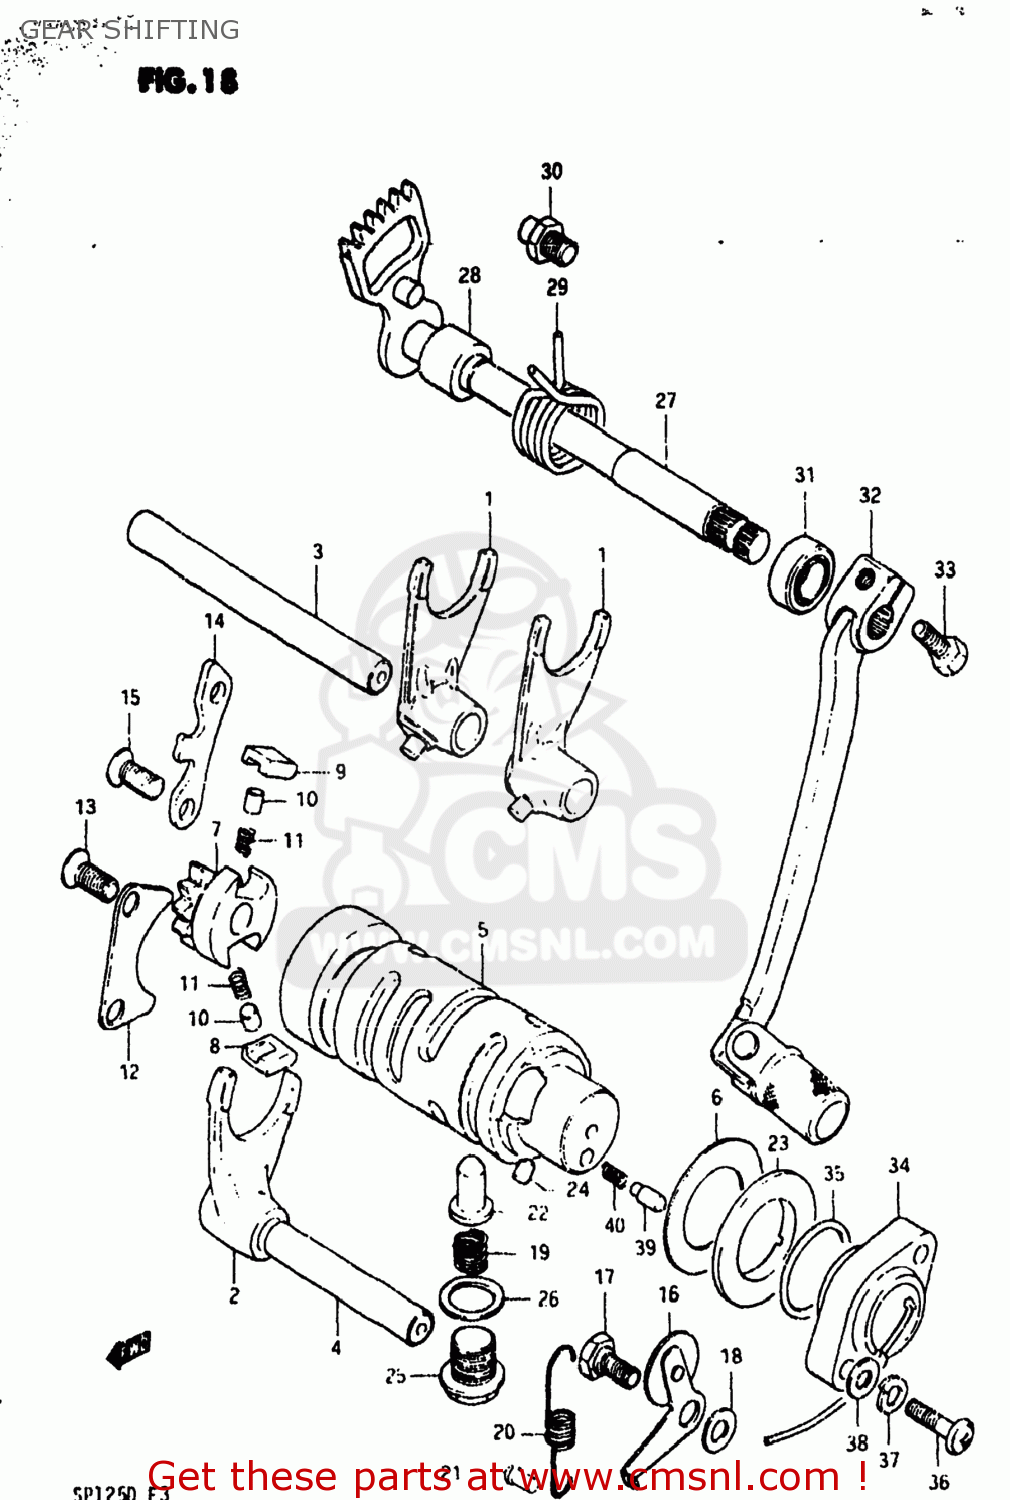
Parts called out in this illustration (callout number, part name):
1	FORK,GEAR SHIFT NO.1
2	FORK,GEAR SHIFT NO.3
3	SHAFT,GEAR SHIFT FORK
4	SHAFT,GEAR SHIFT FORK
5	CAM,GEAR SHIFT
6	WASHER,THRUST
7	RETAINER,GEAR SHIFT CAM
8	PAWL,GEAR SHIFT NO.1
9	PAWL,GEAR SHIFT NO.2
10	PIN(5X8)
11	SPRING
12	LIFTER,GEAR SHIFT PAWL
13	SCREW
14	GUIDE,GEAR SHIFT CAM
15	SCREW
16	STOPPER,GEAR SHIFTING
17	BOLT
18	WASHER
19	SPRING
20	SPRING
21	RIVET
22	STOPPER,GEAR SHIFT CAM NO.2
23	PLATE,GEAR SHIFT CAM STOPPER
24	PIN 4X6
25	PLUG (14X12)
26	GASKET(14X19.2X2) (NAS)
27	SHAFT,GEAR SHIFT
28	SPACER(12X20X15.3)
29	SPRING
30	STOPPER,GEAR SHIFT CAM
31	OIL SEAL
32	LEVER ASSEMBLY,GEAR SHIFTING
33	BOLT
34	TERMINAL BASE,NEUTRAL SWITCH
35	O-RING (D:2.4 ID:26.2)
36	SCREW 5X20
37	LOCK WASHER
38	WASHER
39	PIN(5X15.5)
40	SPRING
